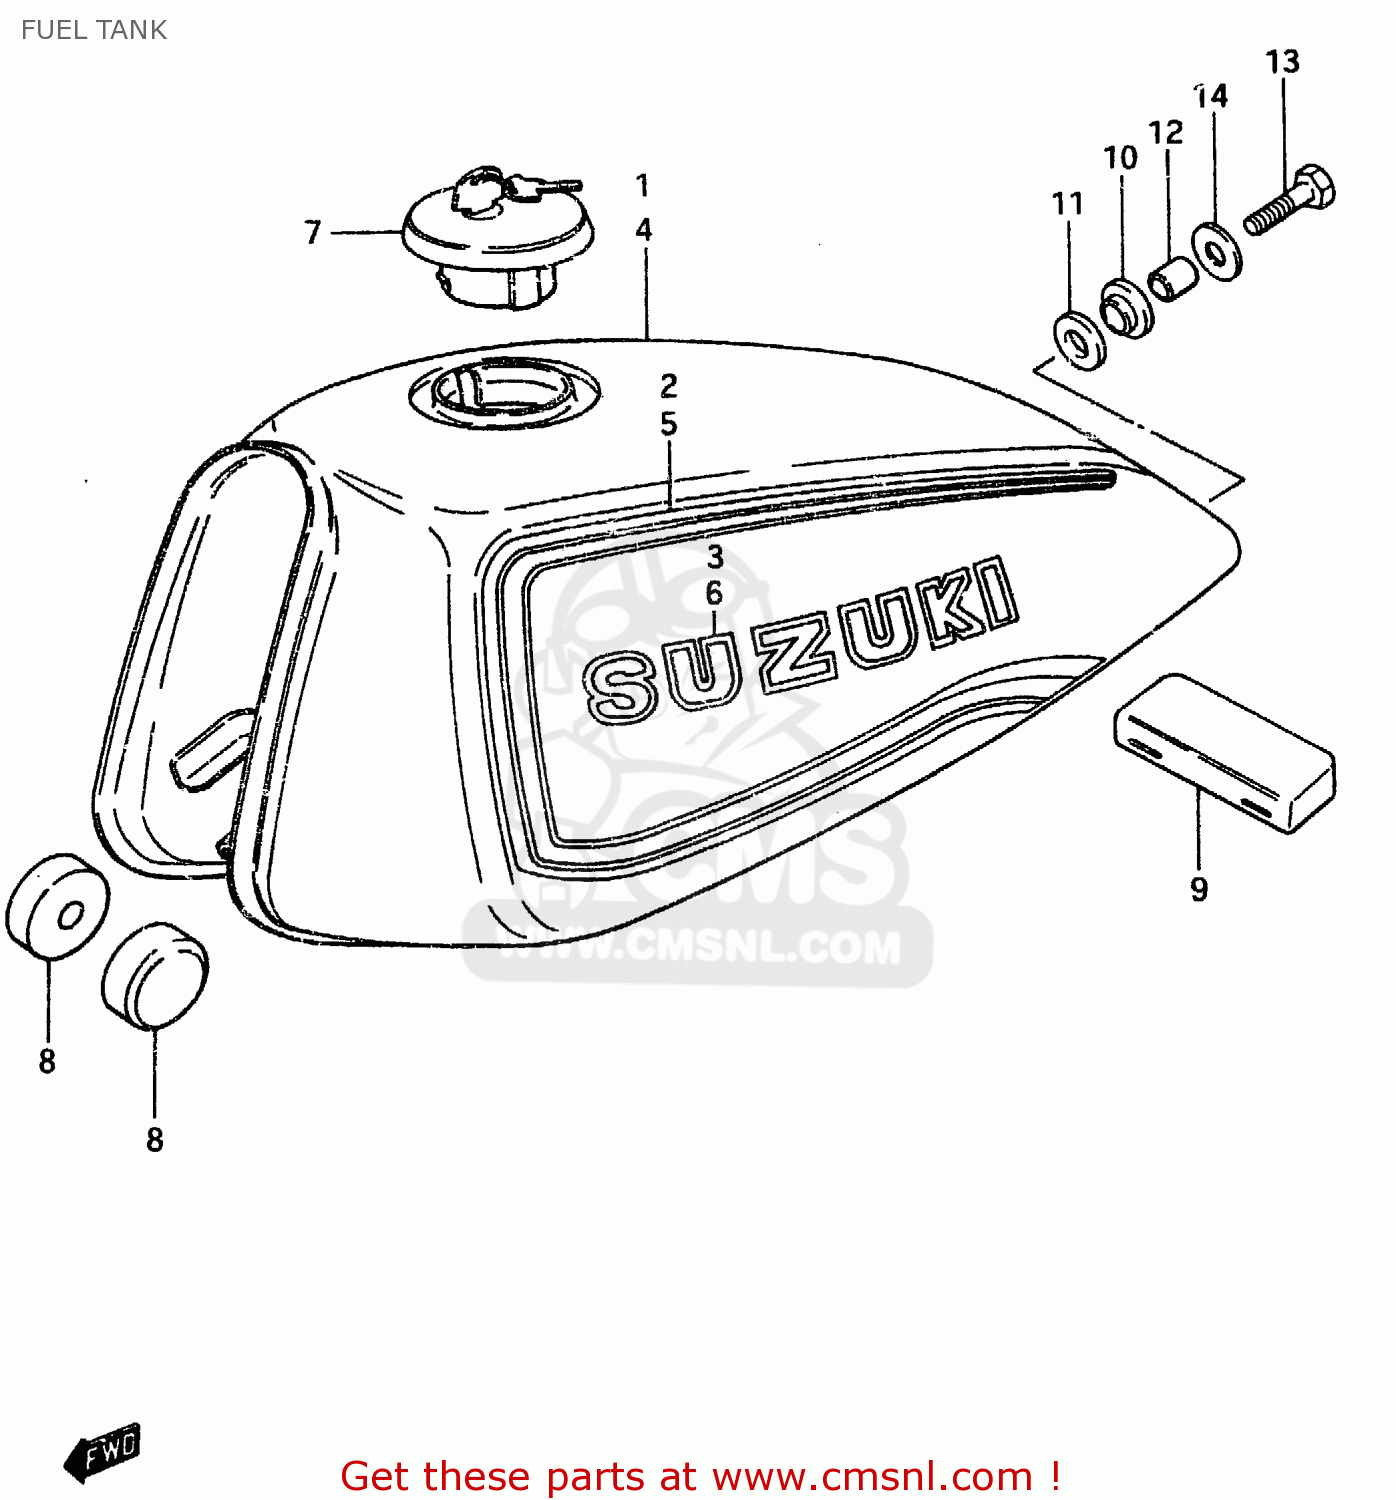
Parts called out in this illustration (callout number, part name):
1	TANK, FUEL (RED)
2	TAPE SET
3	EMBLEM (GOLD)
4	TANK, FUEL (BLUE)
5	TAPE SET
6	EMBLEM (GOLD)
7	CAP SET,FUEL TANK
8	CUSHION
9	CUSHION,FUEL TANK CTR
10	CUSHION
11	CUSHION
12	SPACER(8.5X12X19)
13	BOLT
14	WASHER (8.5X29X1.6)
